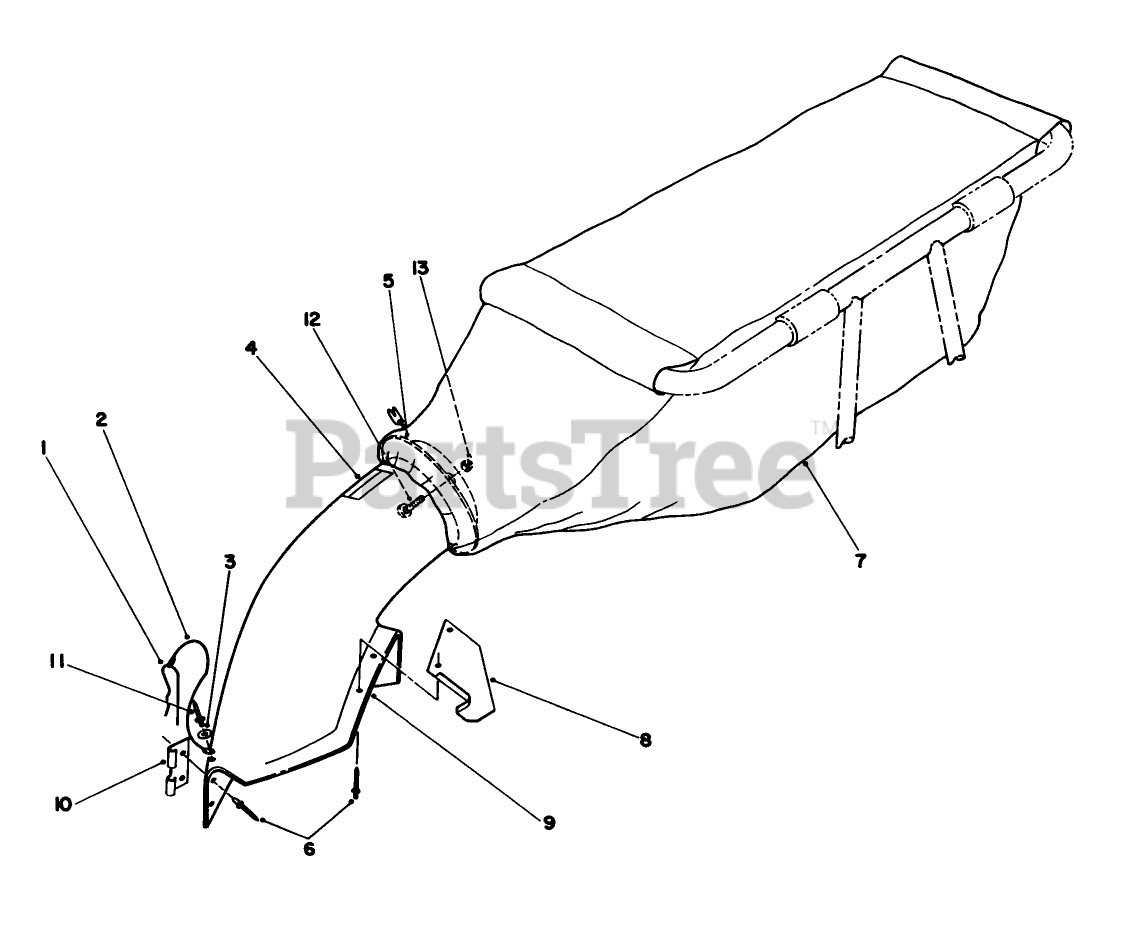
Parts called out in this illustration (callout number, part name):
1	PIN-LOCKING, CHUTE
2	LANYARD
3	WASHER-PLAIN
4	DECAL-DANGER
5	Ring-Bagger
6	RIVET-BLIND
7	BAG ASSEMBLY
8	CHUTE SUPT BRKT
9	Chute Assembly (Incl. Ref. #1-6, & 8, 10-13)
10	BRACKET-MOUNTING, CHUTE
11	RIVET-BLIND
12	SCREW-CARR
13	NUT-LOCK, NI
